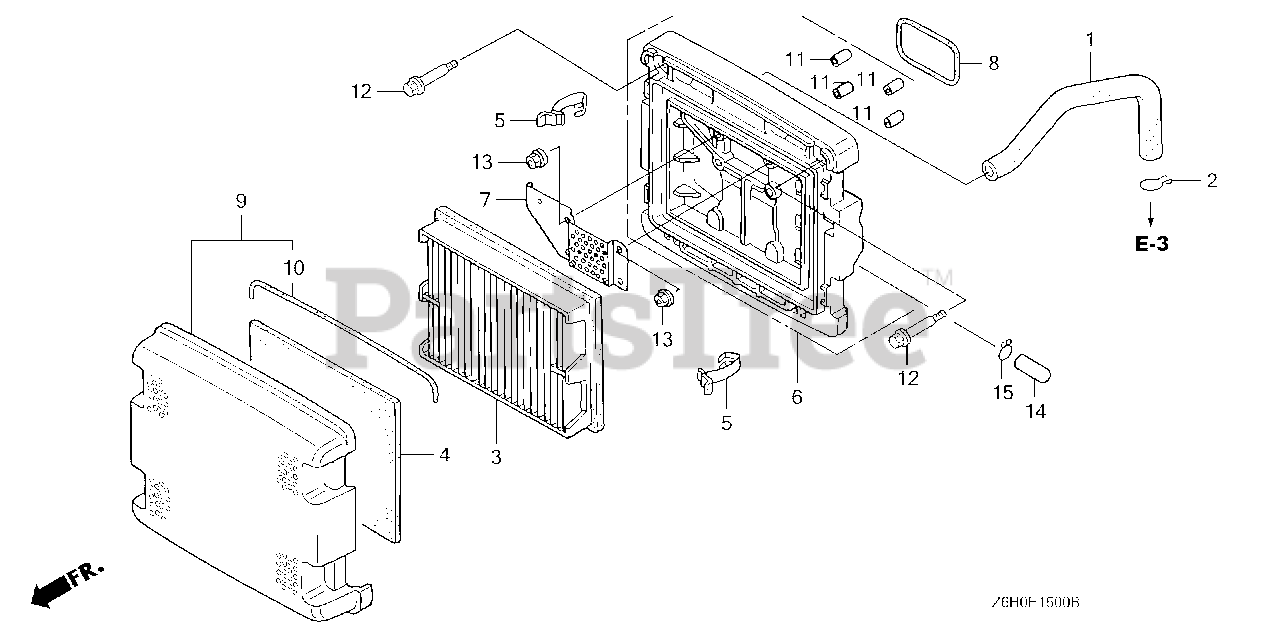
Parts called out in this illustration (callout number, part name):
1	TUBE, BREATHER
2	CLIP, BREATHER TUBE
3	ELEMENT, AIR CLEANER
4	FILTER (OUTER)
5	CLIP, AIR CLEANER
6	HOUSING, AIR CLEANER
7	CAP, AIR CLEANER
8	GASKET, AIR CLEANER
9	COVER ASSY., AIR CLEANER
10	SEAL, AIR CLEANER COVER
11	COLLAR A, AIR CLEANER
12	BOLT, SPECIAL (5MM)
13	NUT, FLANGE (6MM)
14	CAP, SEALING
15	CLIP, TUBE (B10)
